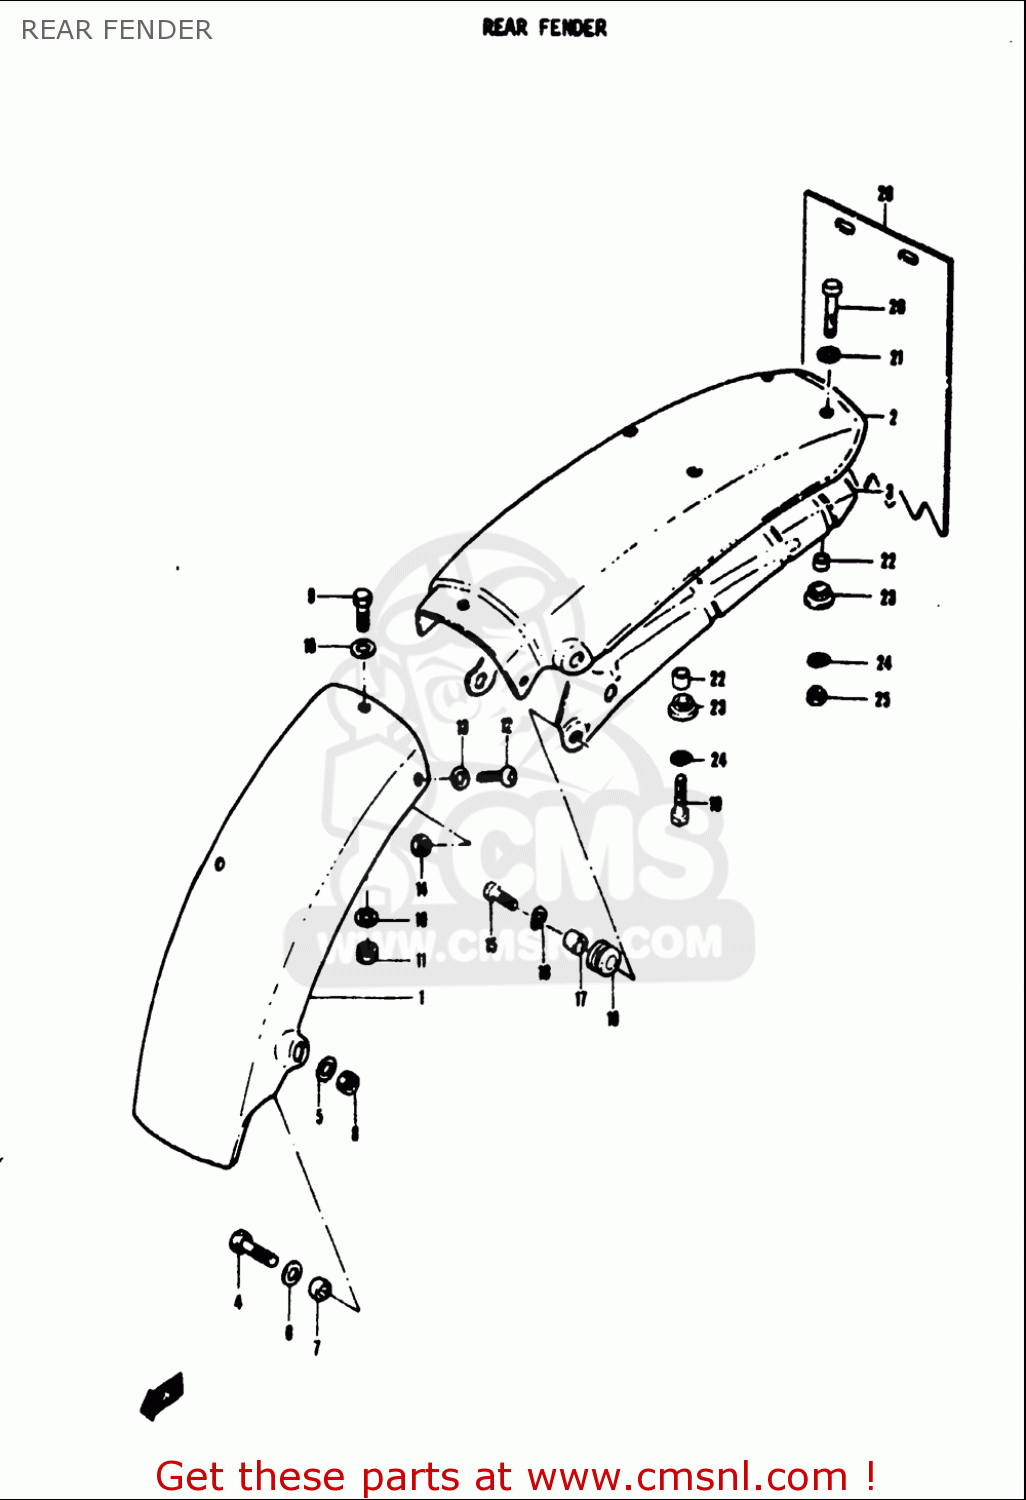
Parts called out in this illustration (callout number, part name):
4	BOLT
5	WASHER
6	WASHER(6.5X20X1.6)
7	SPACER
8	NUT
9	BOLT(6X14)
10	WASHER(6.5X16X1.2)
11	NUT
12	SCREW
13	WASHER
14	NUT
15	BOLT
16	WASHER,LOCK
17	SPACER(6.1X9X7.5)
18	CUSHION
19	BOLT(6X18)
20	BOLT
21	WASHER
22	SPACER
24	WASHER,LOCK
25	NUT
